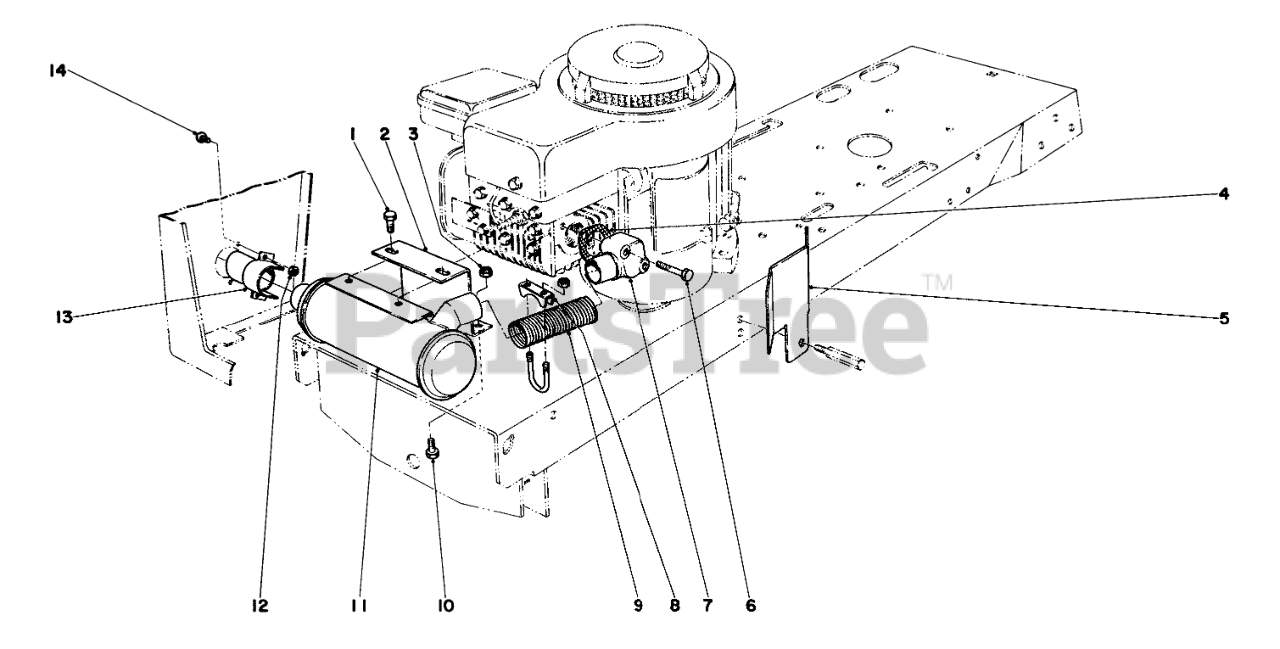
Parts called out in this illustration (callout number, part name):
1	SCREW-HH
2	Muffler Support
3	NUT-LOCK, CONE
4	Gasket
5	Heat Baffle
6	Capscrew
7	Elbow Exhaust
8	Muffler Clamp
9	Exhaust Tubing
10	SCREW-HH
11	Muffler
12	NUT-LOCK, SIDE
13	Exhaust Tip
14	SCREW-PPH
